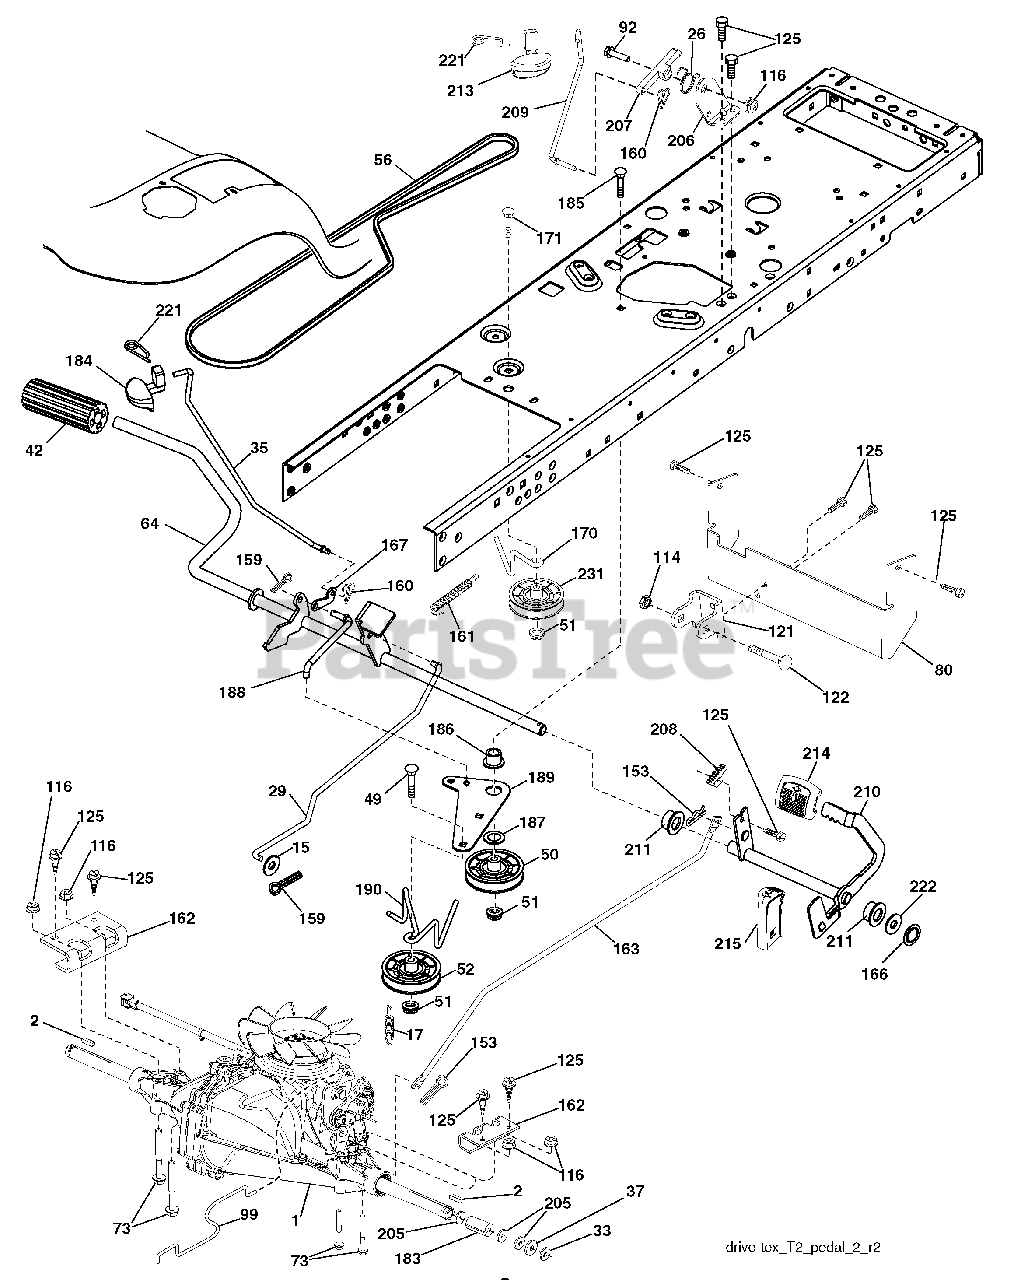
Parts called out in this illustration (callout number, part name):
2	Key
15	Washer 13/32 x 13/16 x 16 Ga.
17	Spring, Brake
26	Spring Return Cruise
29	Rod, Brake
33	Ring E
35	Rod, Brake, Park
37	Washer 25/32 x 1-1/4 x 16 Ga.
42	Cover, Foot Pedal
49	Bolt
50	Pulley Idler Flat
51	Lock Nut 3/8-16
52	Idler V-Groove 910" Offset
56	V-Belt, Drive
64	Shaft Asm. Pedal Brake Control
73	Bolt 5/16-18 Gr. 5
80	Strap Torque
92	Bolt Fin Hex 5/16-18 unc x 1.25
99	Rod Asm Bypass Spring
114	Nut Lock 5/16-18 unc
116	Nut Lock Hex Flange 5/16-18
121	Bracket Strap Torque
122	Bolt 5/16-18 x 2.50
125	Screw 5/16-18 x 3/4
153	Retainer Spring
159	Pin Cotter 1/8 x 3/4
160	Retainer Clip
161	Spring, Return, Clutch
162	Adapter Transaxle
163	Rod Pedal Control
166	Nut Push .625
167	Latch Brake Parking
170	Keeper Belt Centerspan
171	Bolt
183	Spacer Axle
184	Handle Parking Brake
185	Bolt
186	Spacer Retainer
187	Washer
188	Link Clutch Ground Drive
189	Bellcrank Ground Drive
190	Keeper Bellcrank Ground Drive
205	Washer 25/32 x 1-5/8 x 16 Ga.
206	Bracket Mount Latch Cruise
207	Latch Control Cruise
208	Gear Sector Control Cruise
209	Rod Control Cruise
210	Rockr Asm. Pdeal Control
211	Bearing Nylon
213	Knob control Cruise
214	Pad Pedal Forward
215	Pad Pedal Reverse
221	Retainer Spring Clip Handle
222	Washer 21/32 x 1-1/4 10 Ga.
231	Idler V-Groove 1.688
